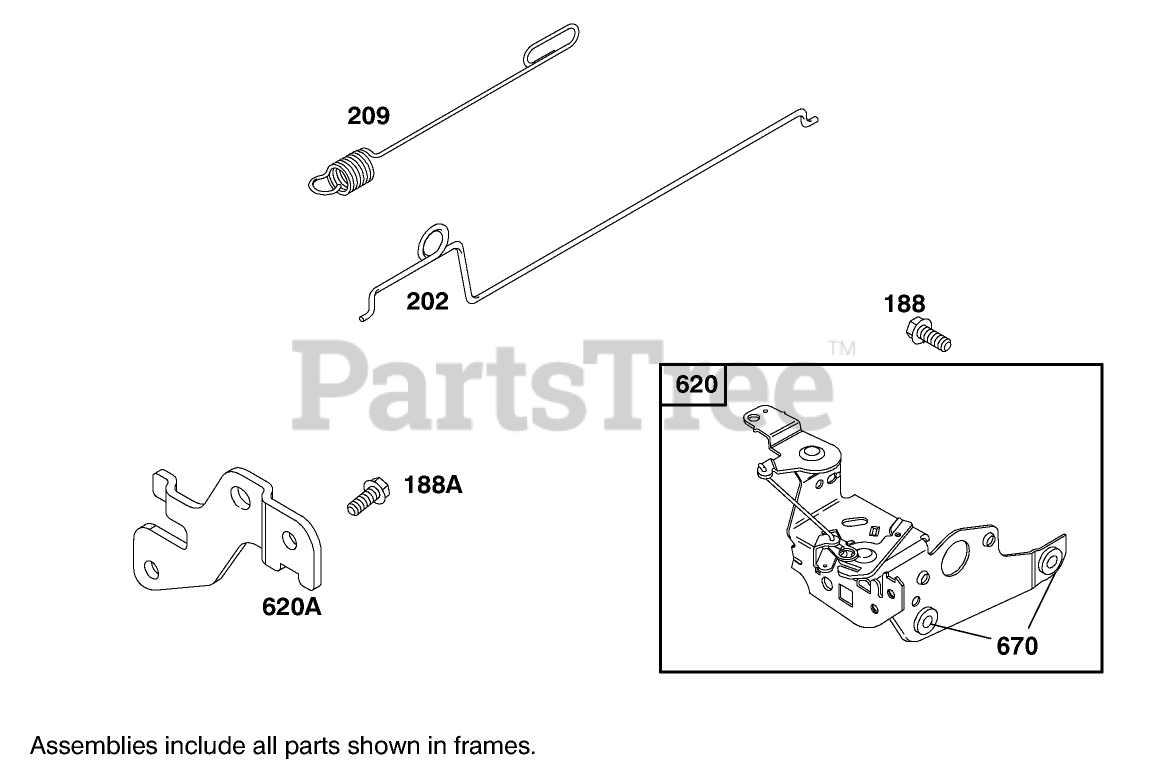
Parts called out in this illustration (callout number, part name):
188	Screw-Hex.
188A	Screw-Hex.
202	Link-Govemor
209	Spring-Governor
620	Bracket-Carburetor
670	Spacer
